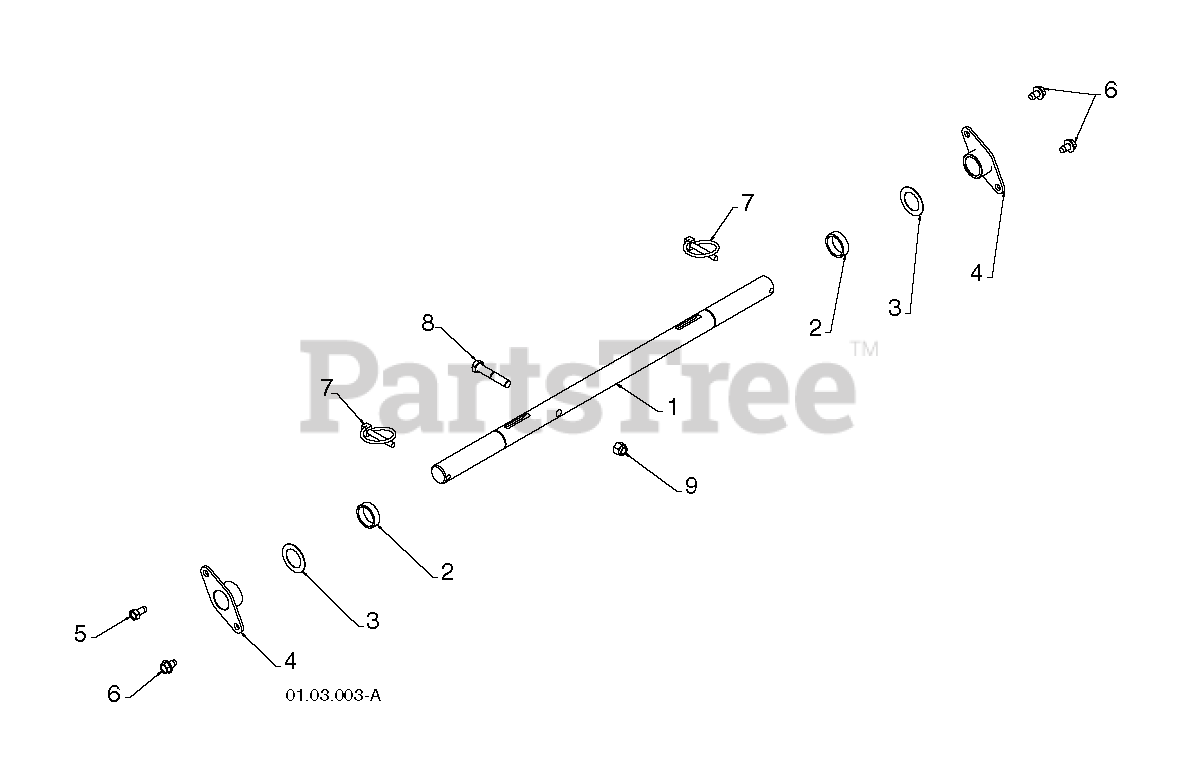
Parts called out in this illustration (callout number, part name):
1	SHAFT.AXLE.POWER.STEERING.HYD
2	SPACER.AXLE.RH
3	WASHER 1.00
4	BEARING, AXLE
6	SCREW LT
7	PIN KLIK, 1/4
8	CAP.SCREW.HEX.HD.3/8-16
9	NUT
